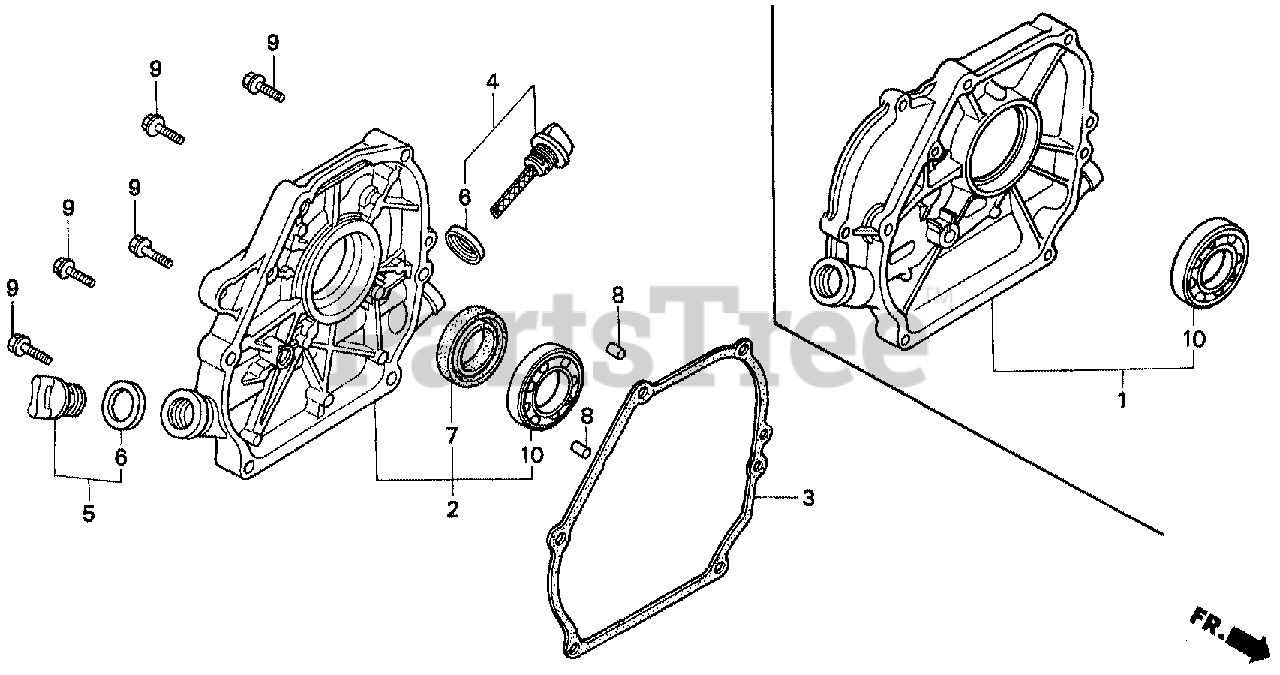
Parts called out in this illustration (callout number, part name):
2	COVER ASSY., CRANKCASE (U-TYPE)
3	GASKET, CASE COVER (NON-ASBESTOS)
3	GASKET, CASE COVER
4	CAP ASSY., OIL FILLER
5	CAP ASSY., OIL FILLER
6	GASKET, OIL FILLER CAP
7	OIL SEAL (25X41X6)
8	PIN A, DOWEL (8X14)
9	BOLT, FLANGE (8X32)
10	BEARING, RADIAL BALL (6205)
